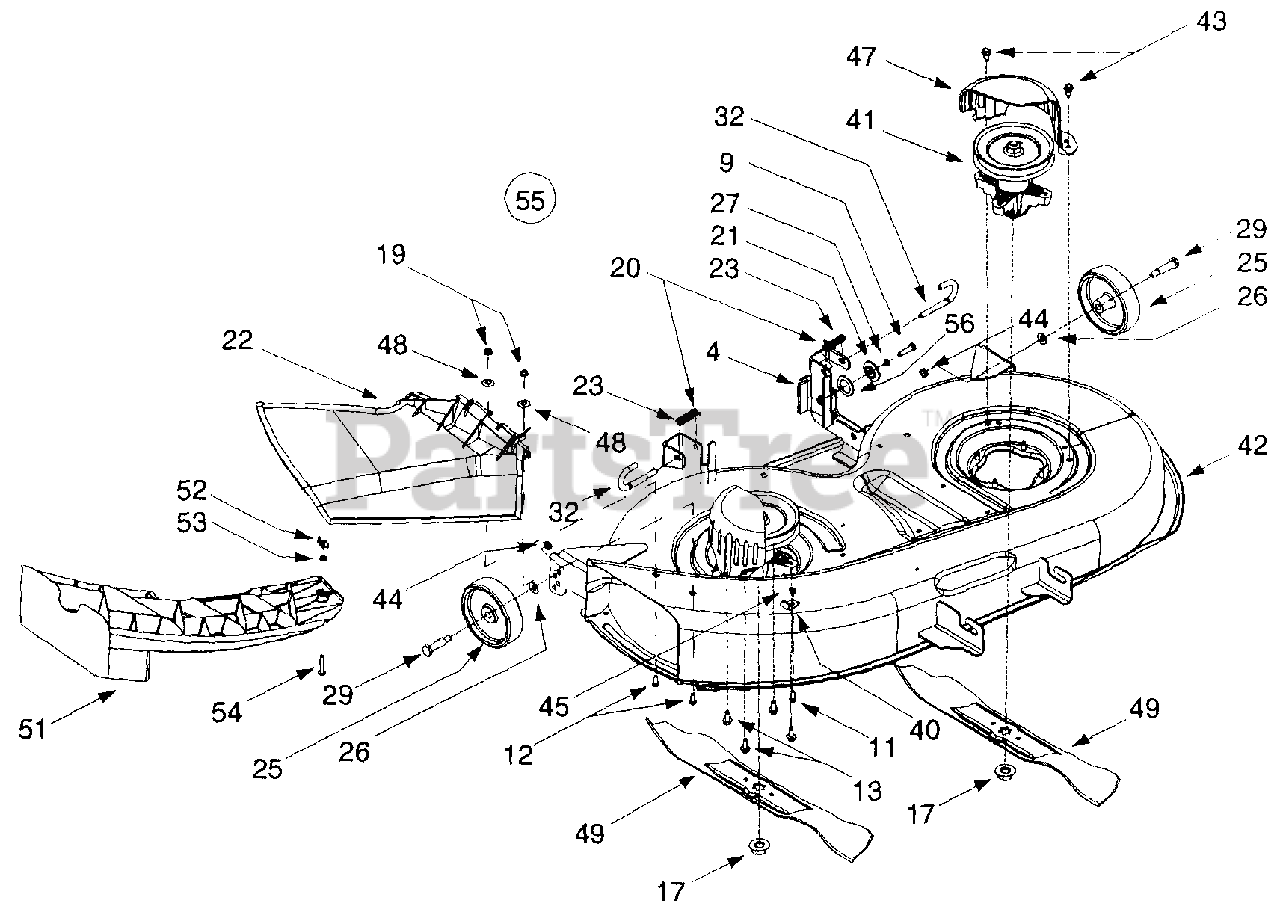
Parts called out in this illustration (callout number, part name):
9	Hex Cap Screw, 5/16-18 x 1.25
11	Self Tapping Screw, 5/16-18 x .875
12	Hex Cap Screw, 1/4-20 x .62
13	Self Tapping Screw, 5/16-18 x .75
17	Hex Flange Nut, 5/8-18
19	Hex Flange Lock Nut, 1/4-20
20	Internal Cotter Pin, .072 x 1.12
21	Deck Adjustment Gear
22	Side Discharge Chute Assembly
23	Compression Spring, .406 x .531 x 1.75
25	Deck Wheel, 5 x 1.38
26	Bell Washer, .401 x .87 x .063
27	Lock Washer, 5/16
29	Shoulder Spacer, .498 x 1.53
32	Deck Release Pin
41	Spindle Assembly, 5.75 Dia
43	Self Tapping Screw, 5/16-18 x .625
44	Top Lock Jam Nut, 3/8-16
45	Hex Sems Nut, 1/4-20
47	Belt Cover
48	Bell Washer, .265 x .75 x .062
49	Three-in-one Blade, Star Center, 21.23
51	Mulch Plug, 42-inch Decks
52	Wing Nut, 1/4-20
53	Center Lock Nut, 1/4-20
54	Hex Cap Screw, 1/4-20 x 1.25
